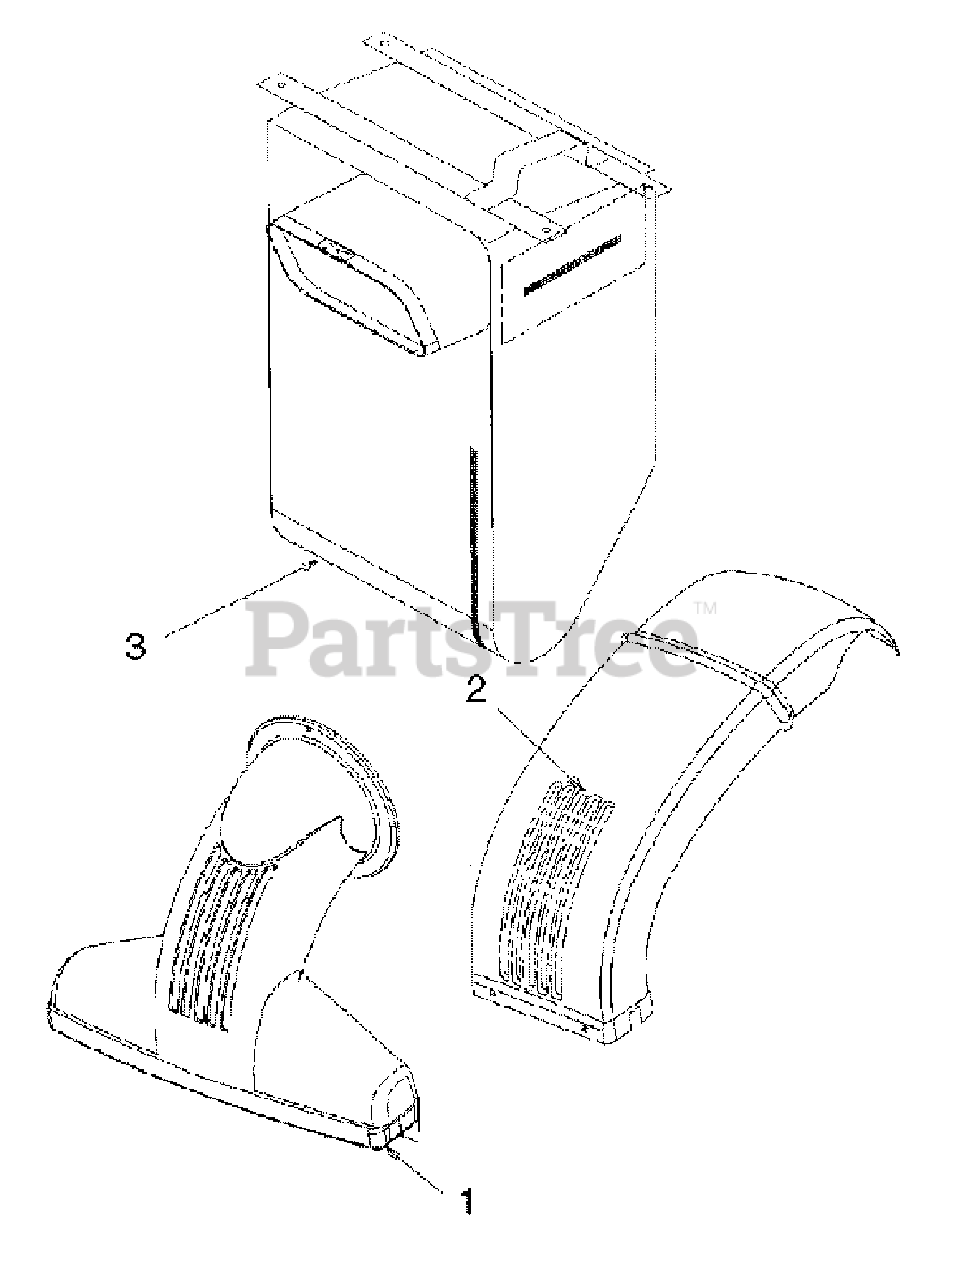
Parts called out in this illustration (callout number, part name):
1	Nozzle Assembly, Vacuum
2	Chute, Discharge
3	Bag, Vacuum
